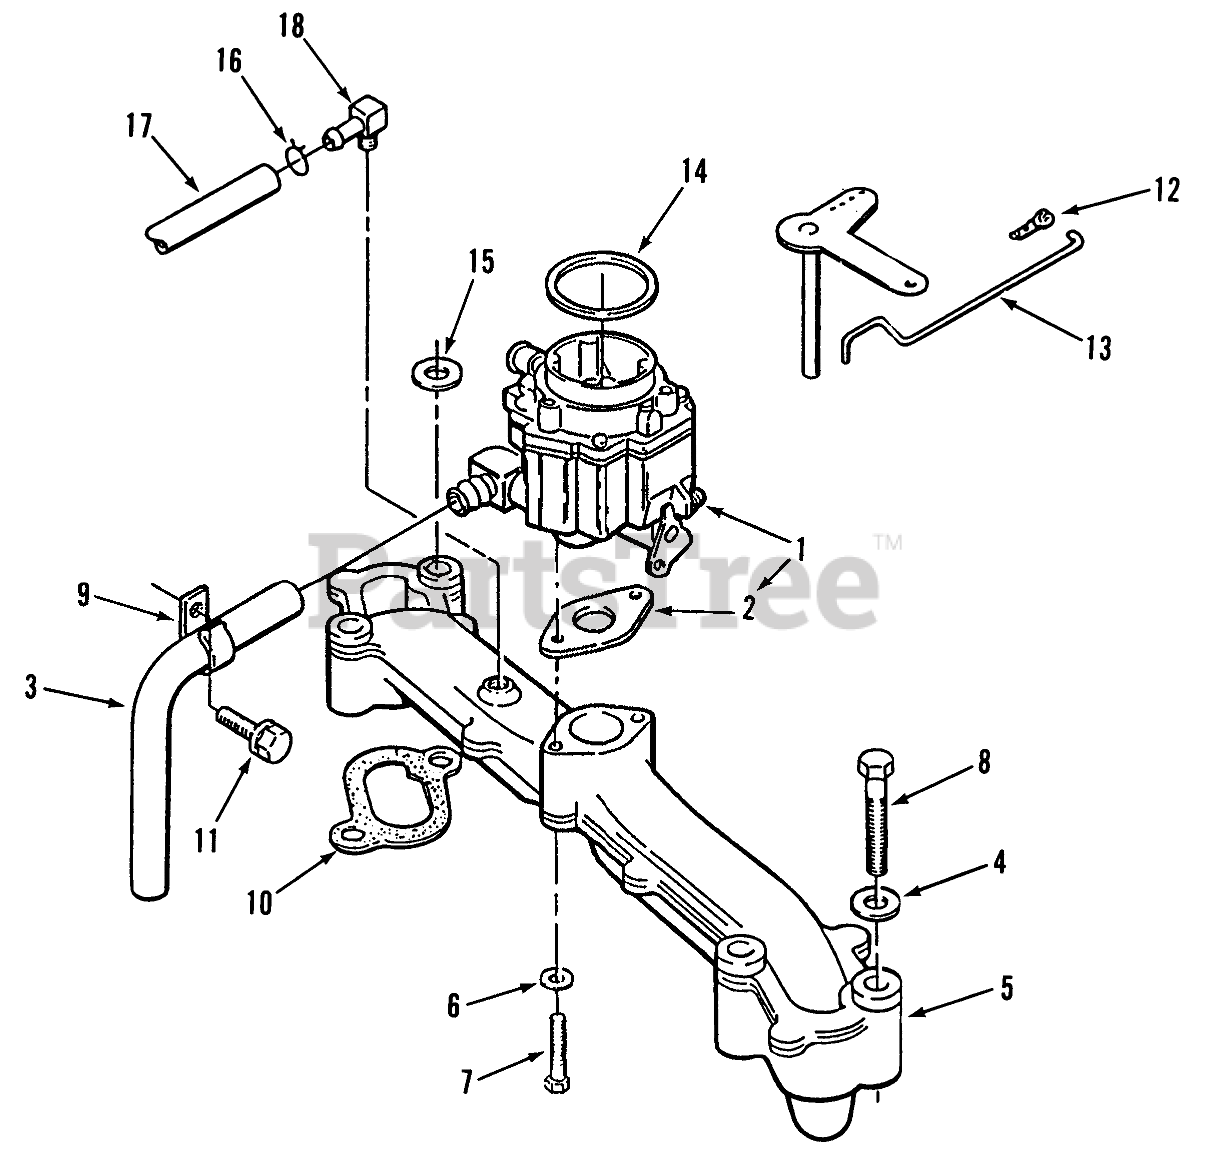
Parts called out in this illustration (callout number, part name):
1	Carburetor (Includes Mounting Gasket, Elbow and "O" Ring) See section 9-9 for complete carburetor breakdown)
2	Gasket
4	Washer
5	Intake Manifold
6	Washer-Lock
7	Screw Hex Hd. 1/4-20 x 1-3/8
9	Clip
10	Gasket
11	Bolt
12	Retaining Clip
13	Governor Control Rod
14	O-Ring
15	FLAT WASHER
16	Clamp .44" Dia.
17	Hose 3.25"
18	Barbed Fitting
